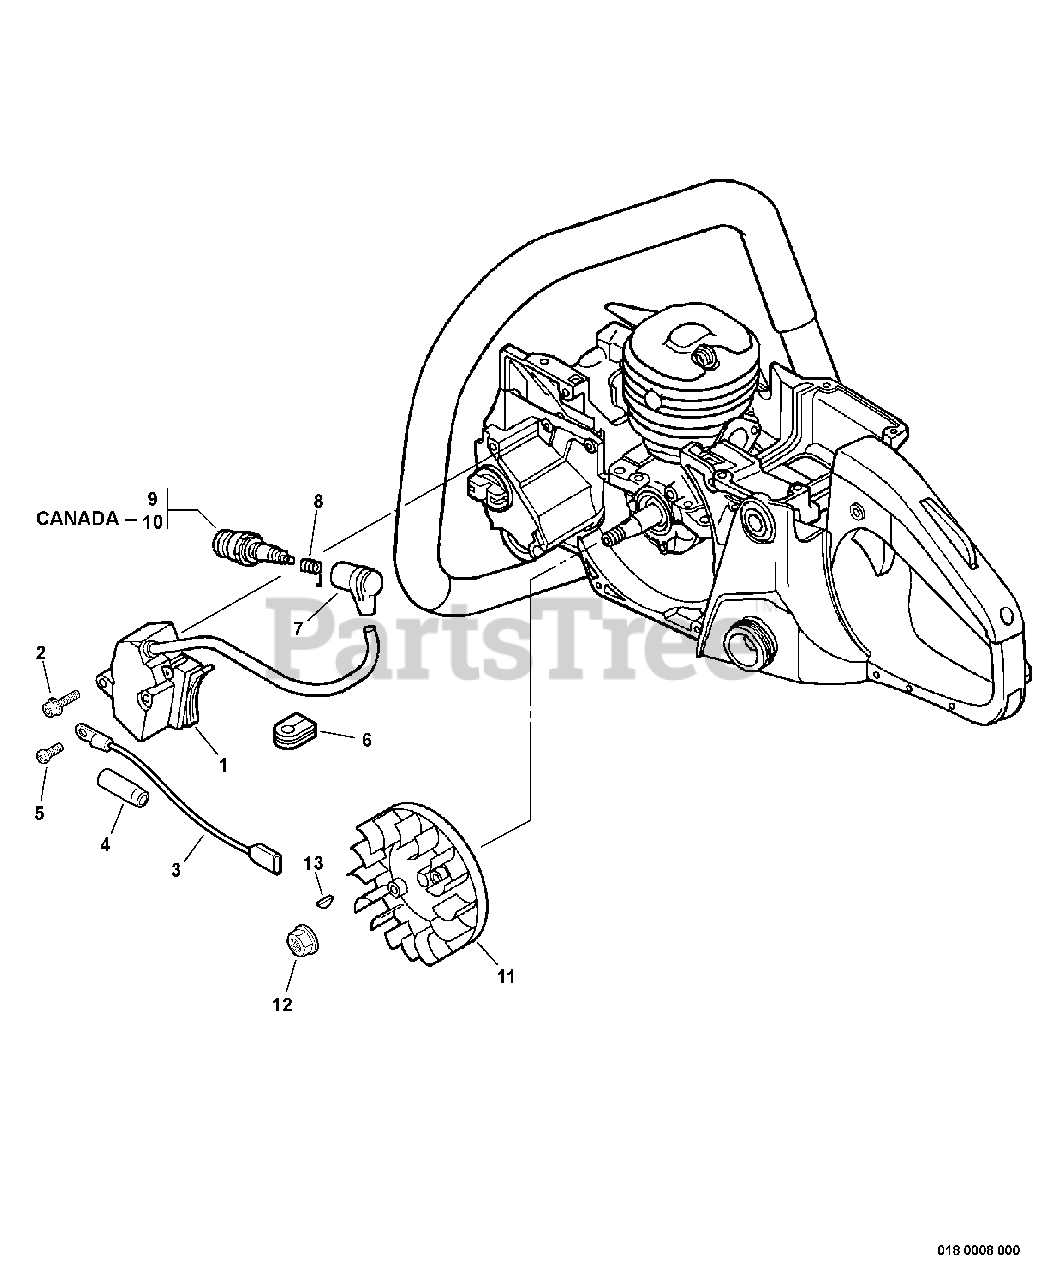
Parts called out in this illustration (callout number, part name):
1	COIL, IGNITION
2	SCREW - 4X30
3	LEAD - GROUND
4	BOOT, CONNECTOR
5	SCREW - 4X6
6	GROMMET
7	CAP, SPARK PLUG
8	TERMINAL, SPARK PLUG CAP
9	SPARK PLUG -- BPM-8Y
10	SPARK PLUG -- BPMR-8Y
11	FLYWHEEL
12	NUT - 8 -- FLANGE
